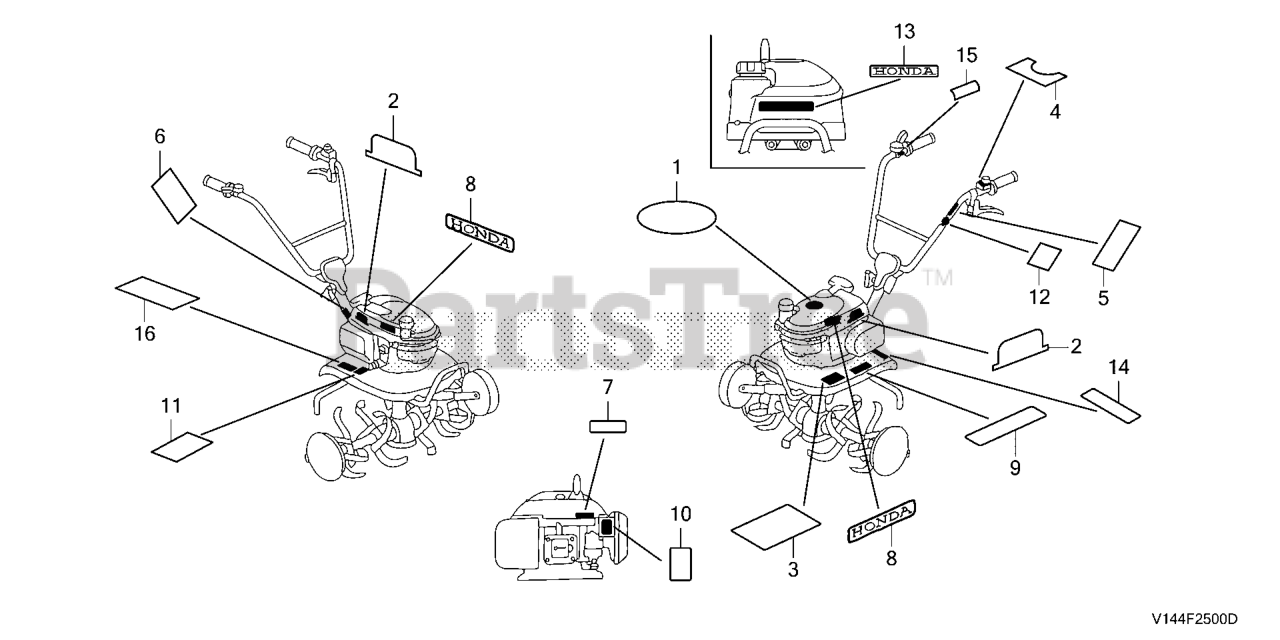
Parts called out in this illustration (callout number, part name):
1	MARK, TOP EMBLEM
2	MARK, STRIPE
3	MARK, TINE DANGER
4	MARK, ENGINE SWITCH INDICATION
5	MARK, CLUTCH INDICATION (US)
6	LABEL, OPERATOR WARNING (ENGLISH)
7	MARK, CHOKE
9	LABEL, EX. CAUTION (ENGLISH)
10	MARK, FUEL (EU)
11	MARK, OIL CAUTION
12	MARK, HOLD POSITION
13	MARK, HONDA
14	LABEL, SPARK WARNING
15	MARK, THROTTLE INDICATION
16	LABEL, WARNING
